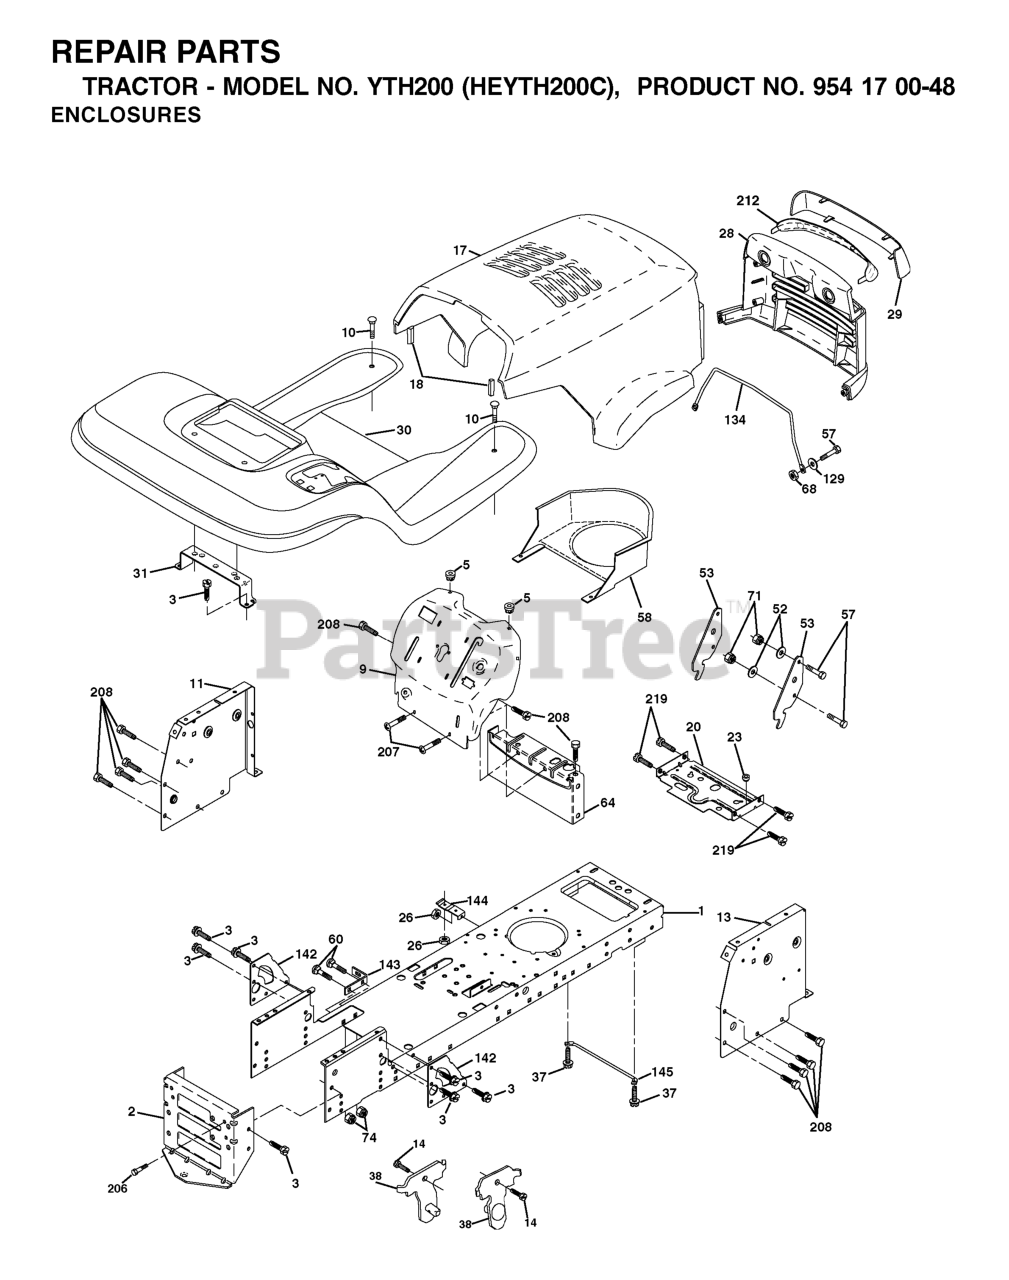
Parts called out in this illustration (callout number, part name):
1	CHASSIS STAMPING
2	DRAWBAR, 12GA
3	SCREW 3/8-16X3/4
5	BUMPER.RUBBER.HOOD
9	DASH(SUBS)
10	BOLT D
11	PANEL.DASH.LH.LTX
13	PANEL ASM, DASH RH
14	SCREW LT
17	HOOD
18	BUMPER HOOD T
20	PLATE MTG.BATTERY/FUEL TANK
23	BUSHING.SNAP.NYL.BLK.
26	NUT
28	GRILL
29	LENS
30	FENDER FOOTREST
31	BRACKET.SUPPORT.FENDER
37	Screw 5/16-18 x 1/2 Hex, Self Tapping 5/16-18 x 1/2
38	BRACKET.ASM.PIVOT.MOWER.REAR
52	WASHER
53	BRACKET PNT PICK OFF LT/PL
57	BOLT
58	DUCT, INTAKE AIR
60	Bolt - Rd. Hd. Sq. Neckiage 3/8 16 x 3/4
64	DASH LOWER
68	NUT
71	NUT.CROWNLOCK.1/4
129	WASHER
134	ROD SUPPORT HOOD LT/PL HUS.
142	PLATE REINFORCEMENT
143	BRACKET, SWAY BAR
144	BRKT, FOOT REST
145	ROD PIVOT CHASSIS/HOOD
206	SHOULDER BOLT 5/16-18TT
207	SCREW, 5/16-18 X 1/2
208	SCREW 3/8-16X1/2
212	INSERT LENS REFLECTOR
219	SCREW
